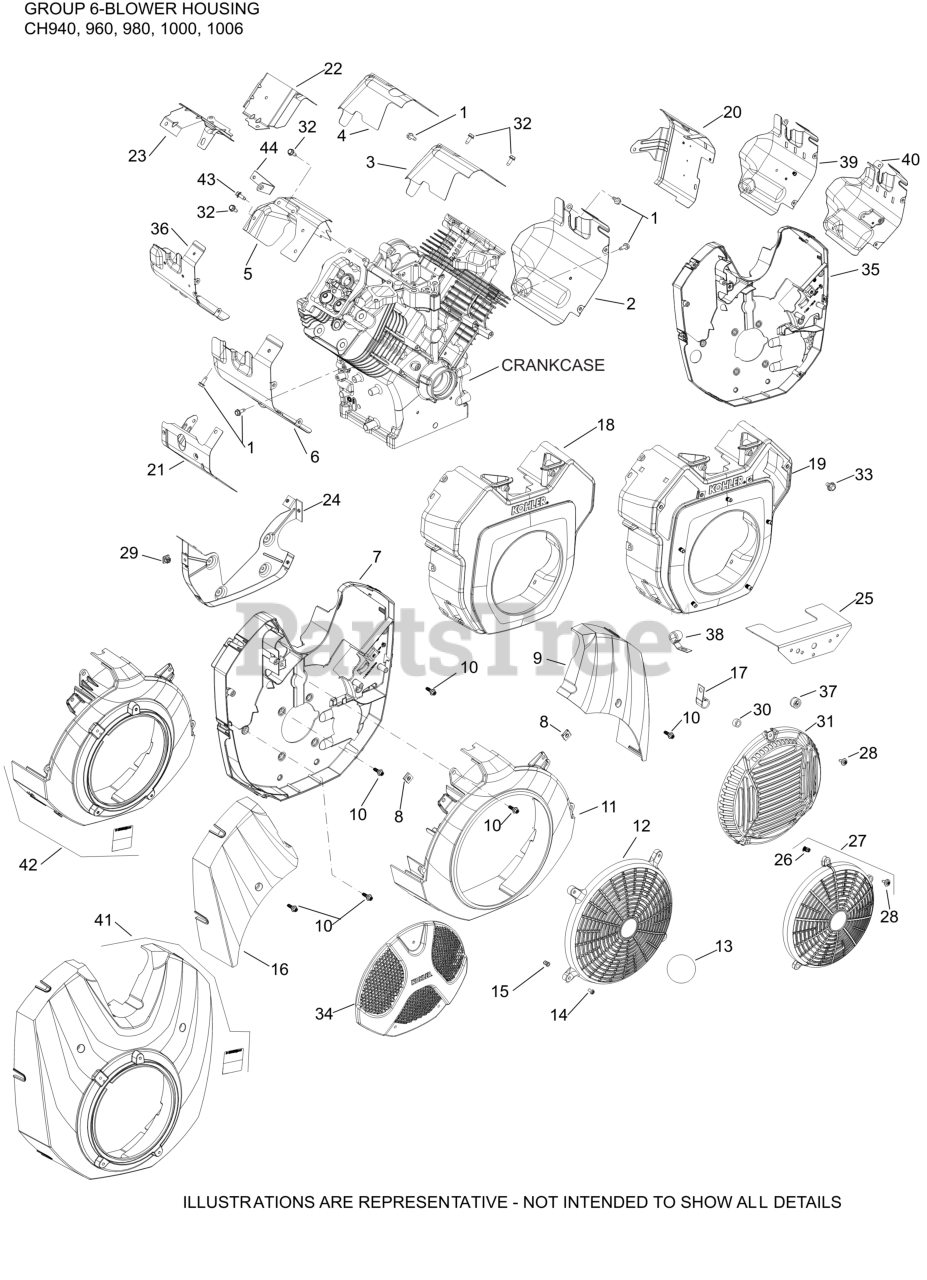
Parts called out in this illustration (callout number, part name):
1	SCREW, THREAD FORMING
4	BAFFLE, VALLEY #1 CYLINDER
5	BAFFLE, VALLEY #2 CYL-USE 62 063 40-S
6	BAFFLE, BARREL (#2 CYL)
7	SHROUD AND CLIP ASSEMBLY
8	CLIP, BAFFLE MOUNTING
9	SHROUD, #1 CYLINDER
10	SCREW, SHD THD FRM
11	KIT, BLOWER HOUSING
16	SHROUD, #2 CYLINDER
32	SCREW, FLG M6x1.0x20
40	BAFFLE, BARREL (#1 CYL)
43	SCREW, THREAD FORMING
44	STRAP, LIFTING
